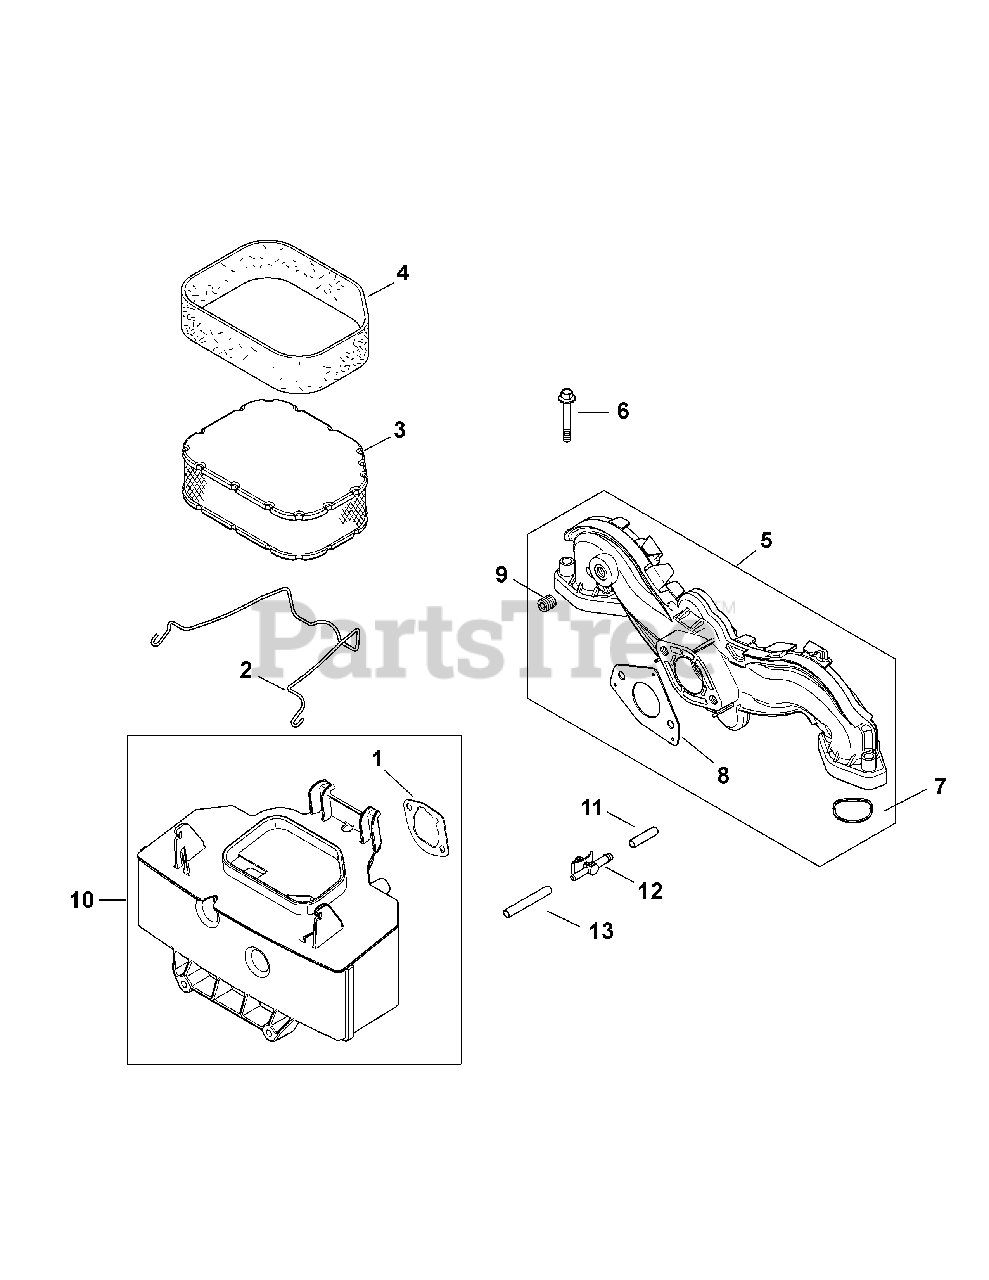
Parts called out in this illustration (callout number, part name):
1	Air Cleaner Base Gasket
2	Air Cleaner Element Latch
3	Air Filter Element
4	Pre-Cleaner Element
5	Intake Manifold Kit
6	Flg. Screw, M6 x 1.0 x 40
7	O-Ring, Intake Port
8	Carburetor Gasket
9	Pipe Plug, 1/8"
10	Air Cleaner Base
12	Evaporative Connector
13	Evaporative Hose, 20"
